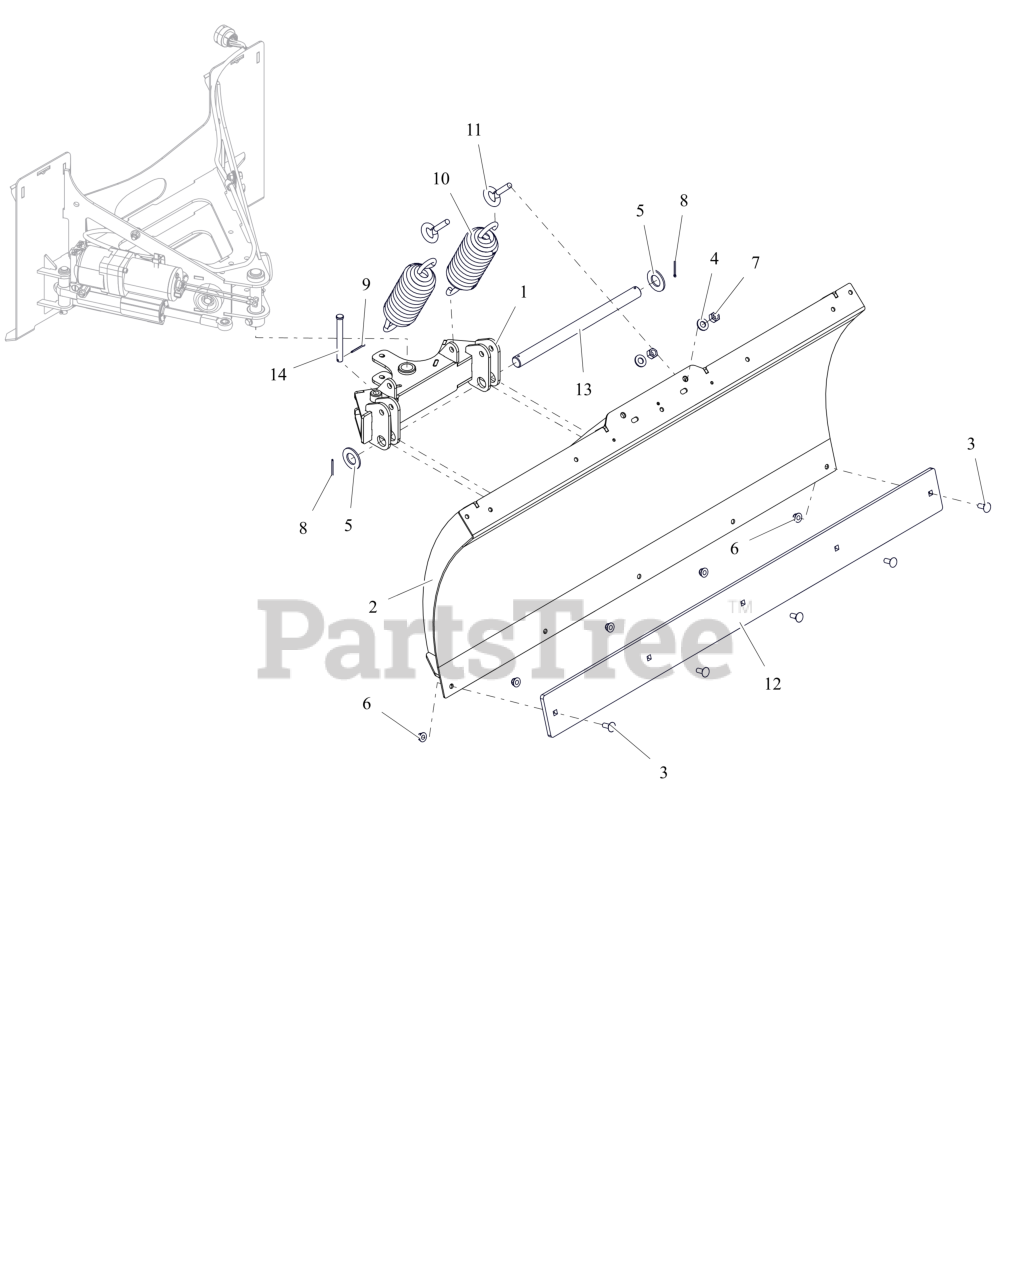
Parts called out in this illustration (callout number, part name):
1	WLDMT, PIVOT SNOW PLOW W/ZERKS
2	WLDMT, BLADE 48"
3	BLT, RHSN .38-16X1.00 G5 ZCC
4	WSHR,FLT .531X1.062X.095 ZCC
5	WSHR, FLT 1.062X2.000X.134 ZCC
6	NUT,NYL-FLG .38-16 GF ZCC
7	NUT,LK-CTR .50-13 GA ZCC
8	PIN, CTR .12X1.50 EXTPRSQCT ZC120
9	PIN,CTR.12X1.25EXTPRSQCT ZC120
10	SPRG, EXTENSION PLOW TRIP
11	EYEBOLT, FORMED 1/2"-13, 4"
12	EDGE, CUTTING, 48" BLADE
13	PIN, TILT
14	PIN, CLEVIS .5 X 4.25
